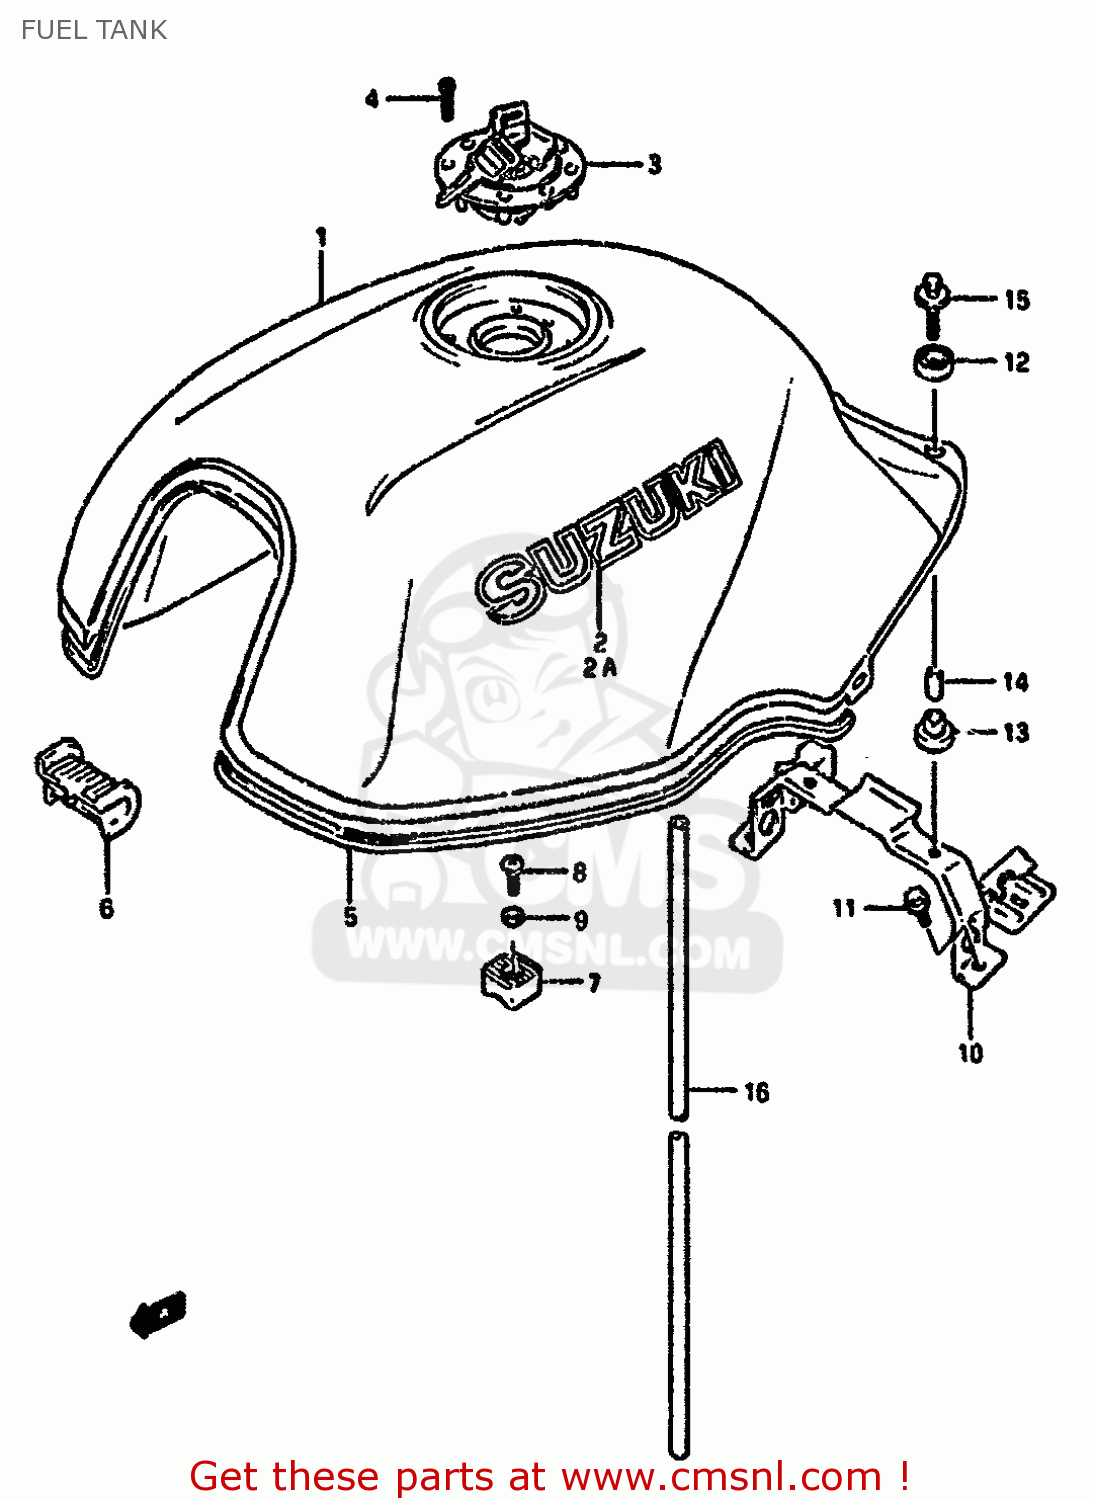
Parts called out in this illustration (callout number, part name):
1	TANK ASSEMBLY,FUEL
2	EMBLEM
2A	EMBLEM,FUEL TANK
3	CAP SET,FUEL TANK
4	BOLT(5X20)
5	MOLDING,FUEL TANK
6	CUSHION,FUEL TANK,FRONT
7	CUSHION,FUEL TANK SIDE
8	SCREW
9	WASHER
10	BRACKET COMP,FUEL TANK
11	BOLT
12	CUSHION
13	CUSHION
14	SPACER
15	BOLT(6X35)
16	HOSE(7X10.2X600)
